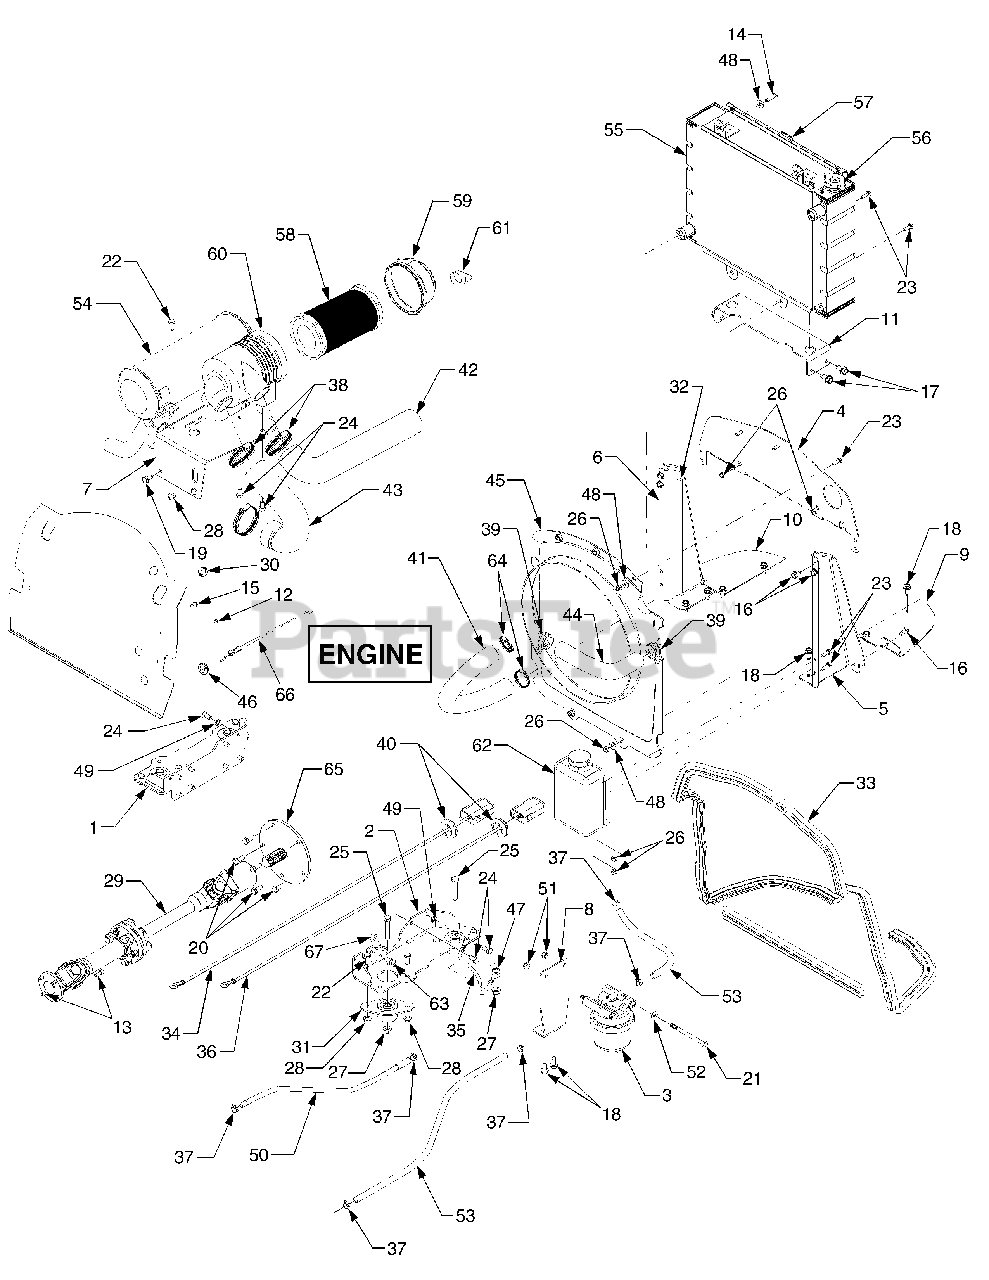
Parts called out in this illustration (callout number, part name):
1	Bracket, Engine LH
2	Bracket, Engine RH
3	Filter Assembly, Fuel
3	Filter Element
4	Plate, Radiator Baffle
4	Graphic, Fan Warning
4	Graphic, Warning
5	Bracket, Radiator Mtg. RH
5	Graphic, Warning
6	Bracket, Radiator Mtg. LH
6	Graphic, Warning
7	Bracket, Muffler Mtg.
12	Screw, Hex Wash Hd Tapp 10-16 x .5
13	Screw, Socket Hd. Cap, 1/4-20 x .62 GR8
14	Screw, Hex Cap 1/4-20 x 1.0 GR5
15	Screw, Hex Wash Hd Tapp 1/4-20 x .5
16	Screw, Hex Wash Hd Tapp 5/16-18 x .5
17	Screw, Hex Wash Hd Tapp 3/8-16 x .75
18	Screw, Hex Wash Hd Tapp 5/16-18 x .75
19	Screw, Hex Cap, M8-1.25 x 16
20	Screw, Hex Cap, M8-1.25 x 20
21	Screw, Hex Cap, 5/16-18 x 4.0 GR5
22	Screw, Hex Cap 5/16-18 x .75 GR5
23	Screw, Hex Cap 1/4-20 x .75 GR5
24	Screw, Hex Cap, M8-1.25 x 16
25	Screw, Hex Cap 3/8-16 x 2/0 GR5
26	Nut, Hx Insert Flange Lk, 1/4-20
27	Nut, Hx Insert Flange Lk, 3/8-16
28	Nut, Hx Insert Flnge Lk, 5/16-18
29	Shaft, Drive
30	Plug, Cap
31	Mount, Neoprene Engine
32	Tape, Foam, .625 wide 42in.
33	Seal, Heat Baffle 96in.
34	Wire, Battery Pos.
35	Wire, Ground
36	Wire, Battery Neg.
37	Clamp, Hose
38	Clamp, Adjustable Hose
39	Clamp, Hose
40	Grommet, Hose Guard
41	Hose, Radiator to Engine
42	Hose, Air Filter
43	Hose, Air Inlet
44	Hose, Engine to Radiator
45	Shroud, Fan
46	Grommet, Rubber
47	Washer, External Lock, 3/8
48	Washer, Flat, .28 x .74 x .063
49	Washer, External Lock, 5/16
50	Hose, Fuel Line 77in.
51	Nut, Hx Insert Flnge Lk, 5/16-18
52	Washer, Flat, .344 x .688 x .065
53	Fuel Line, 5/16 ID 92in.
54	Muffler, Engine
55	Grommet, Rubber Mtg.
56	Cap, Radiator, 13psi
57	Screen, Debris
58	Element, Air Cleaner
59	Cap, Air Cleaner
60	Cannister, Air Cleaner
61	Nozzle, Air Cleaner
62	Bottle, Overflow
63	Screw, Hx Cap, M8-1.25:25 GR8
64	Clamp, Hose
67	Bracket, Pump Mtg.
